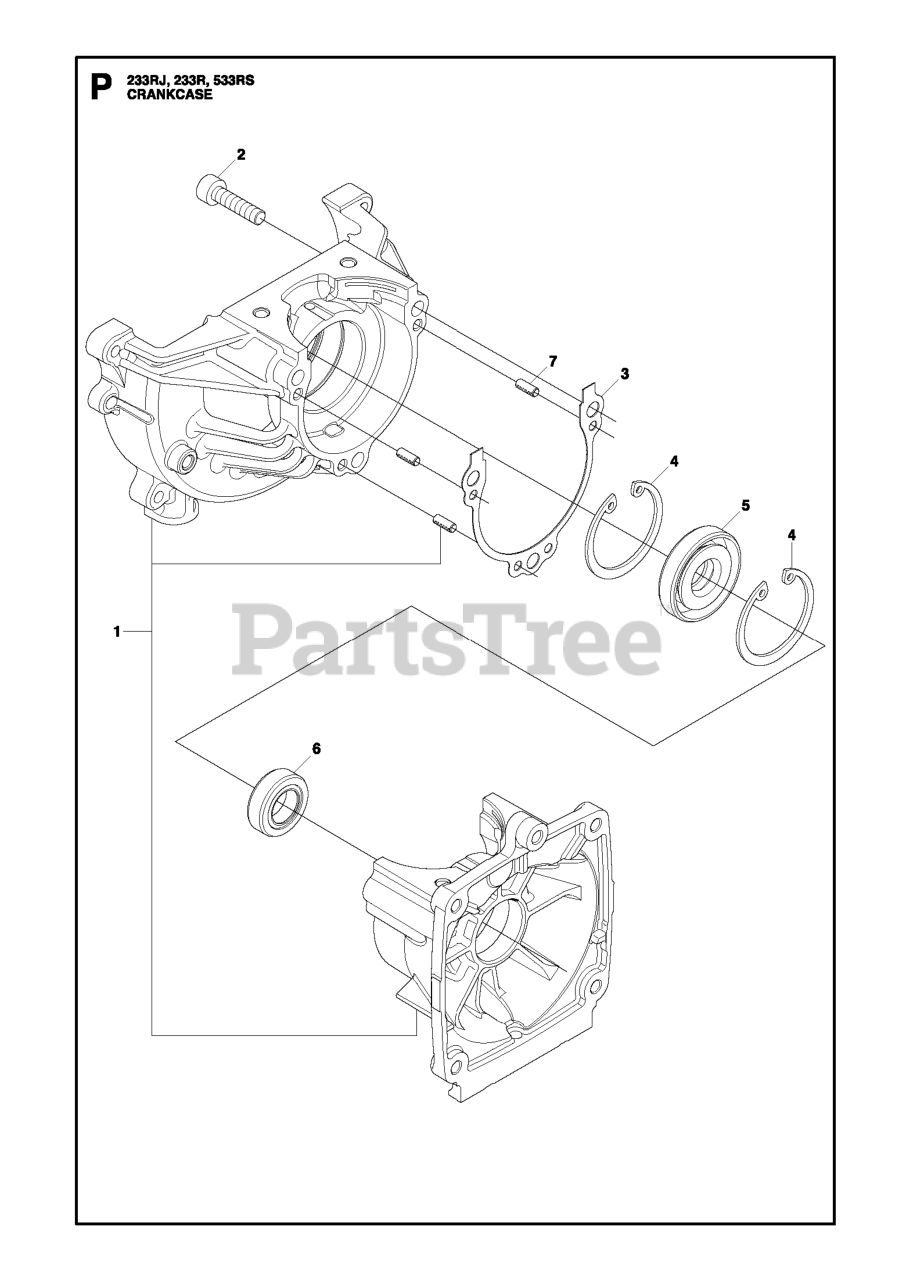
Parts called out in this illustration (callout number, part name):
1	CRANKCASE-C
2	BOLT
3	GASKET CASE
